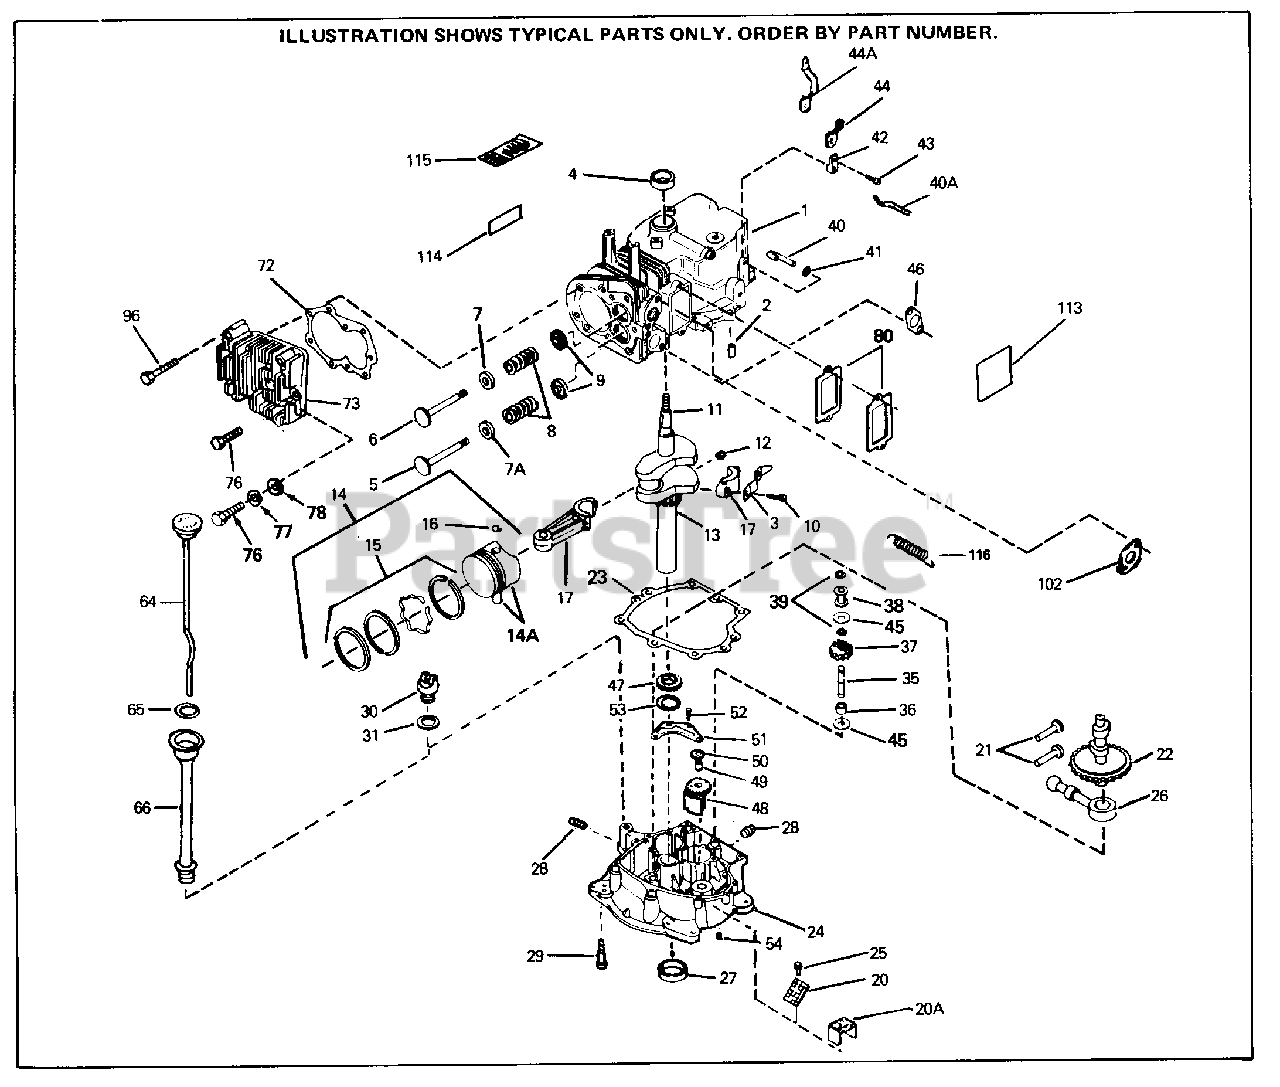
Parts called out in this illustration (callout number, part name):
1	"Cylinder (CI liner)(Incl. 2, 4, 5, 73 , 114) (3-1/16" Bore)
2	Dowel Pin
3	Plate, Lock Used in early production only
4	Seal, Oil
5	Intake Valve (Std)
5	Intake Valve (1/32" OS)
6	Exhaust Valve (Std.)(Incl. 151)
6	Exhaust Valve (1/32" OS) (Incl. 151)
7	Valve Spring Cap
7A	Valve Spring Cap
8	Valve Spring
9	Cap, Lower valve spring
10	Bolt, Connecting rod
11	Crankshaft
12	Pin, Crankshaft gear only)
13	Crankshaft Gear Early production onl y
14	Piston, Pin & Ring Set (Std) 3-1/16" Bore
14	Piston, Pin & Ring Set (.010" OS)
14	Piston, Pin & Ring Set (.020" OS)
14A	Piston & Pin Set (Std)(Incl. 16) 3-1/ 16"
14A	Piston & Pin Set (.010" OS) Incl. 16
14A	Piston & Pin Set (.020" OS) Incl. 16
15	Ring Set (Std) (3-1/16" Bore)
15	Ring Set (.010" OS)
15	Ring Set (.020" OS)
15	Ring Set (Std) (3-1/8" Bore)
16	Piston Pin Retaining Ring
17	Rod Assy., Connecting (Incl. 10)
20A	Screen, Oil filter (Use as required)
21	Lifter, Valve
22	Camshaft
23	Gasket, Mounting flange
24	Flange, Mounting (Incl. 27, 28 & 35)
25	Screw, 8-32 x 5/16" (Use as required)
26	Pump Assy., Oil
27	Seal, Oil
28	Plug, Pipe
29	Screw, 1/4-20 x 1-1/4"
35	Shaft, Mechanical governor
36	Spacer, Governor gear (Incl. 45)
37	Gear Assy., Governor (Incl. 45)
38	Spool, Governor
39	Retaining Ring
40A	Rod, Governor lever
41	Flat Washer
42	Clamp, Governor lever
43	Screw, 8-32 x 5/16"
44A	Lever, Governor
46	Intake Pipe Gasket
72	Gasket, Cylinder head
80	Valve Cover Gasket
102	Gasket, Exhaust
113	Decal, Instruction
114	Decal, Model & Serial Number
115	Decal, Name
